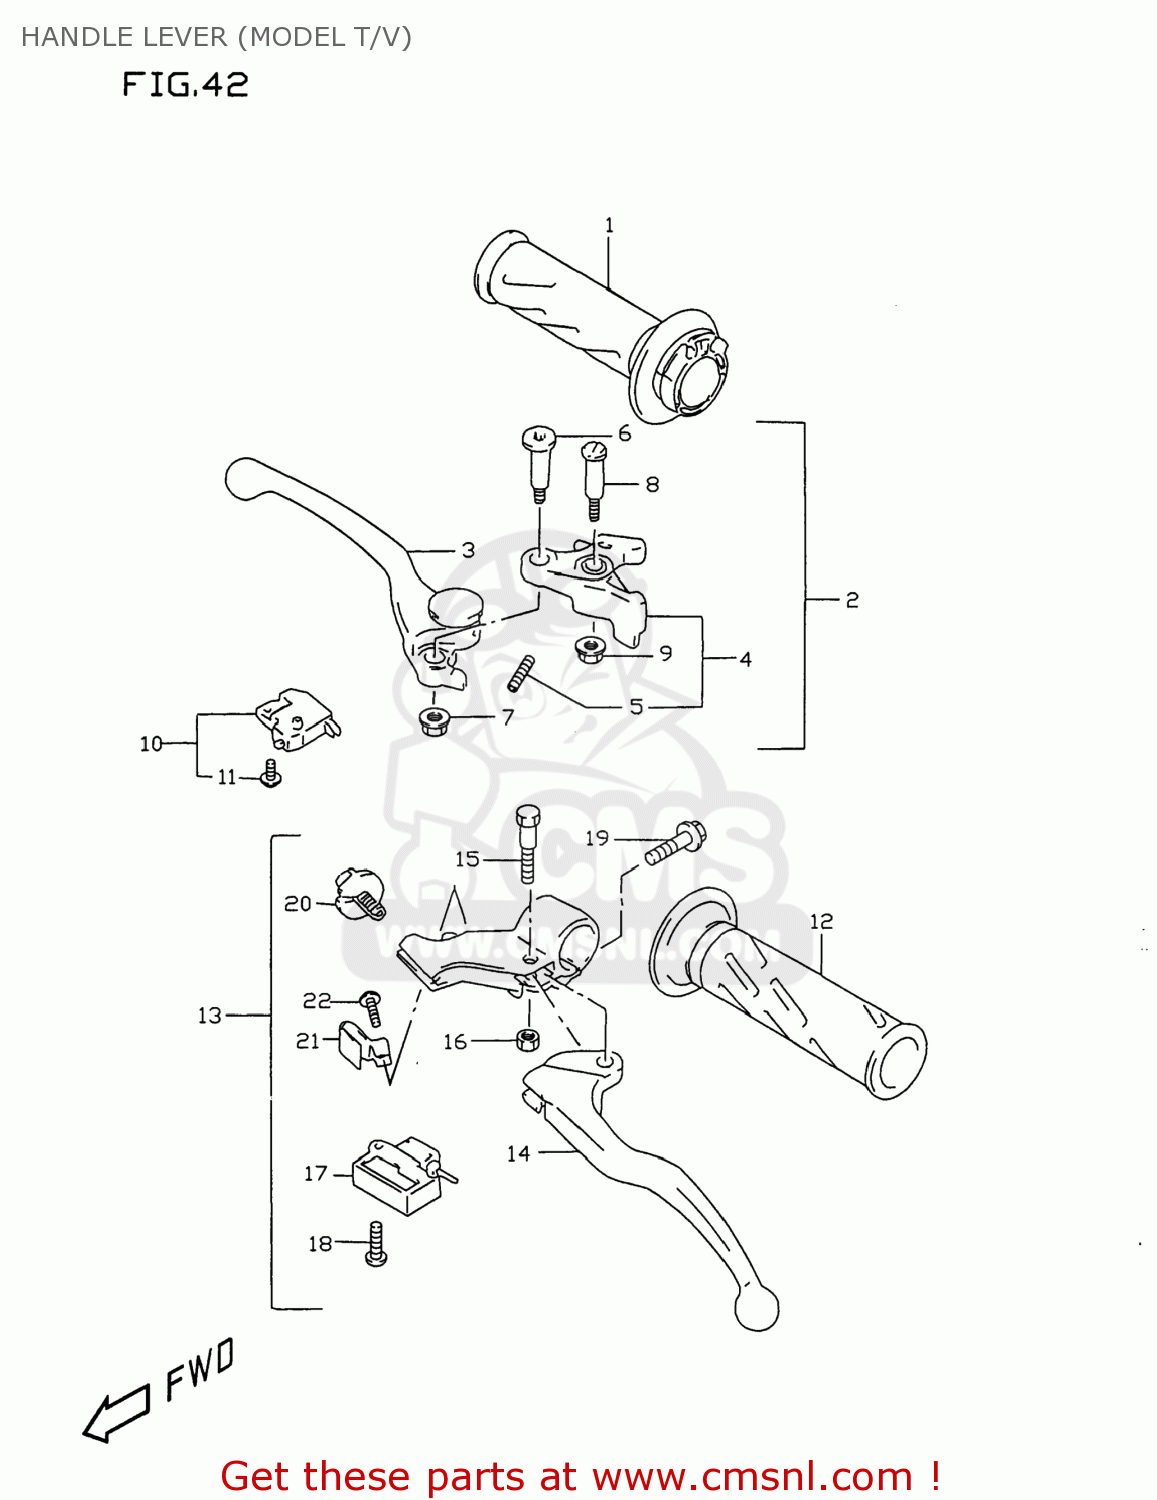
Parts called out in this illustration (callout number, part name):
1	GRIP,THROTTLE
2	LEVER ASSY,BRAKE
3	LEVER,ADJUST
4	KNOCKER
5	SPRING
6	BOLT,LEVER
7	NUT
8	BOLT,LEVER PIVOT
9	NUT
10	SWITCH ASSEMBLY,STOP
11	SCREW
12	GRIP,LEFT
13	LEVER ASSEMBLY,CLUTCH
14	LEVER,CLUTCH
15	BOLT,LEVER SET
16	NUT
17	SWITCH,CLUTCH
18	SCREW
19	SCREW
20	NUT,CABLE ADJUSTER
21	SPRING,ADJUST
22	SCREW,SPRING
